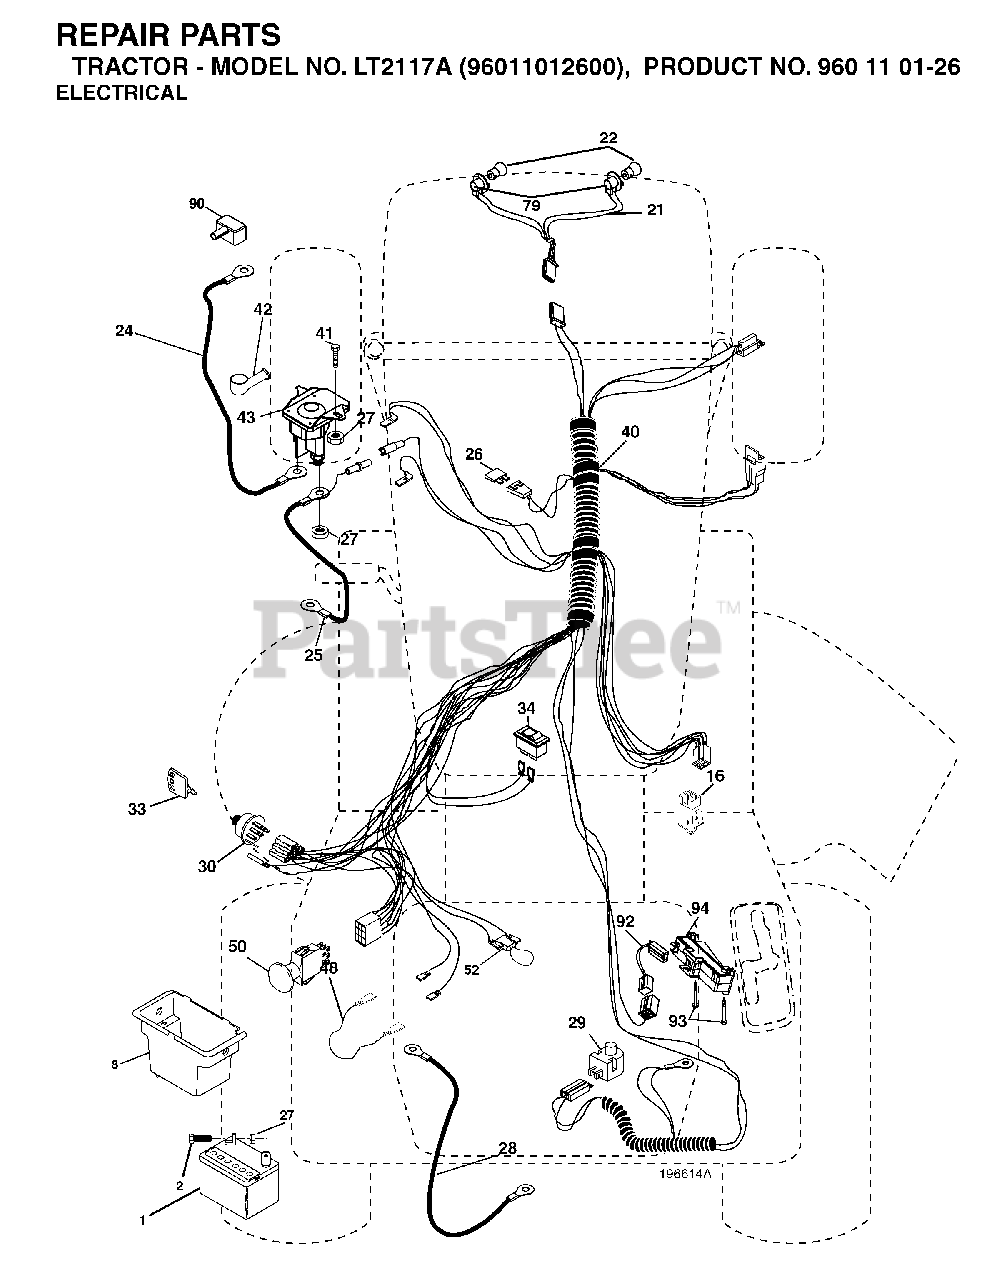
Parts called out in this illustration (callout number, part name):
1	BATTERY 12V .35 AMP
8	BOX.BATTERY.FENDER
16	SWITCH INTERLOOK PUSH-IN
21	HARNESS.W/LIGHT SOCKET
22	LIGHTBULB
24	BATTERY CABLE GT
25	CABLE BATTERY
26	FUSE 20AMP
27	NUT
28	CABLE T
29	SWITCH.SEAT.DP W/RAMPS
30	SWITCH.IGN.DELTA.W.LGH.ROS
33	KEY MLD GEN DELTA
34	SWITCH LT
41	SCREW
42	TERMINAL COVER
43	SOLENOID.W/BRASS.PLUNG
50	PTO SWITCH
52	WIRE PROTECTION LOOP
79	BULB HOLDER ASM.
90	COVER TERMINAL
92	HARNESS.PIGTAIL.CONSLE
93	SCREW.PLASTITE
94	MODULE.REVERSE.ROS
